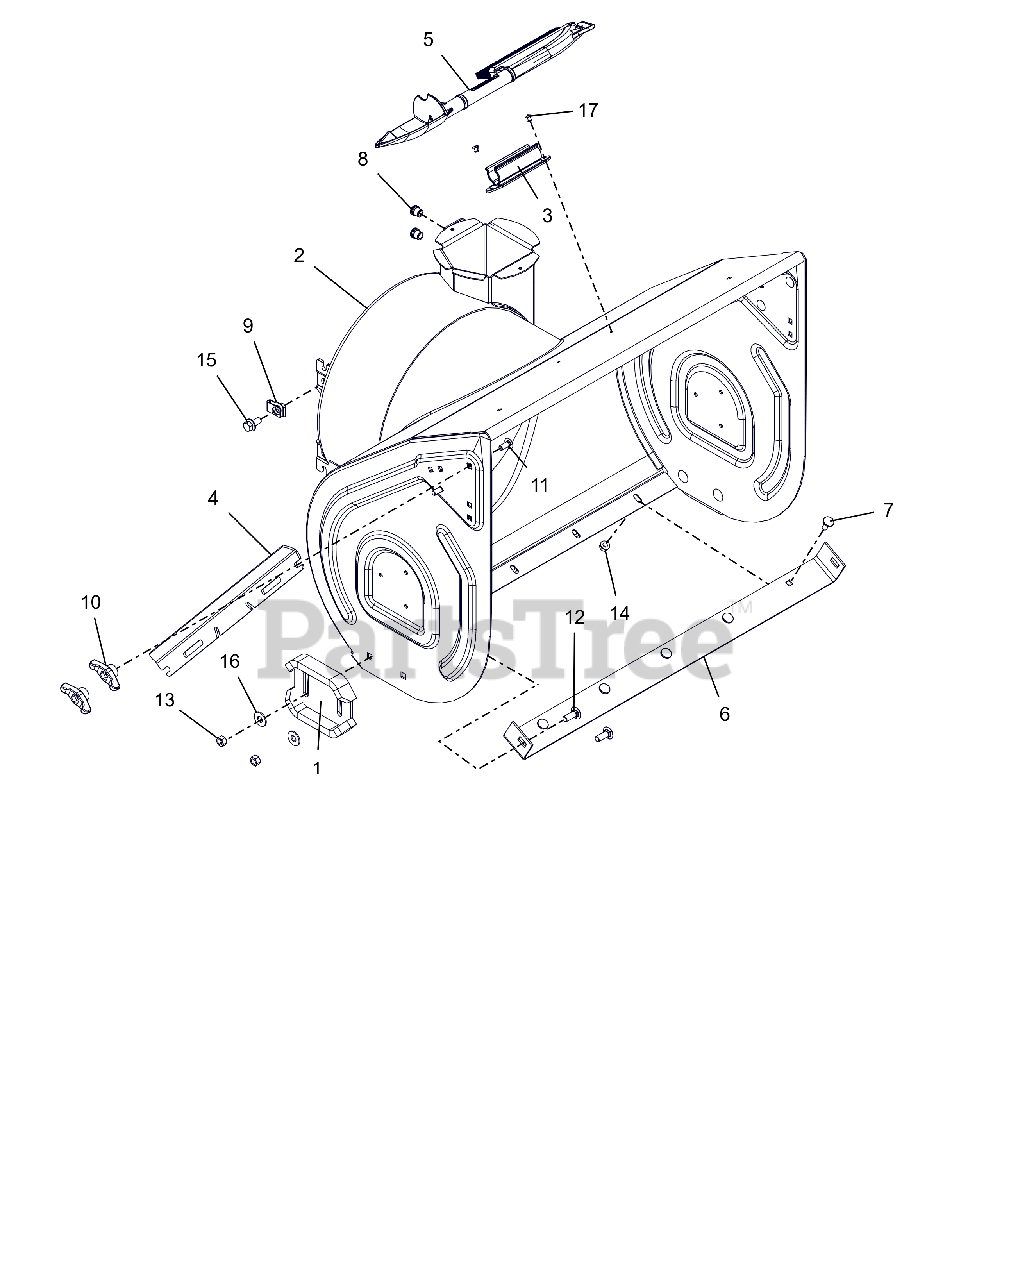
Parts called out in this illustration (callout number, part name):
1	RUNNER, SKID SHOE
2	BLOWER HOUSING W/DECAL 28"
3	MOUNT, SNOW CLEAN OUT
4	CUTTER, DRIFT
5	DEVICE, SNOW CLEAN OUT W/BRUSH
6	BLADE, SCRAPER-28"
7	BOLT, MODIFIED HEAD CARRIAGE
8	NUT,THD,INSERT .38-16 ZC120
9	NUT-RTNR .375-16X.37
10	KNOB,WING .31-18 UNC NYL/TALC
11	BLT, RHSSN.31-18X.750 G5 ZCC
12	BLT,RHSSN .38-16X1.00 G5 ZCC
13	NUT-LK-CTR .38-16 ZC120
14	NUT-LK-TOP-FLG .312-18 GF ZCC
16	WSHR,FLT .438X1.00X.083 ZCC
17	RVT, POP .1875 ZCC
